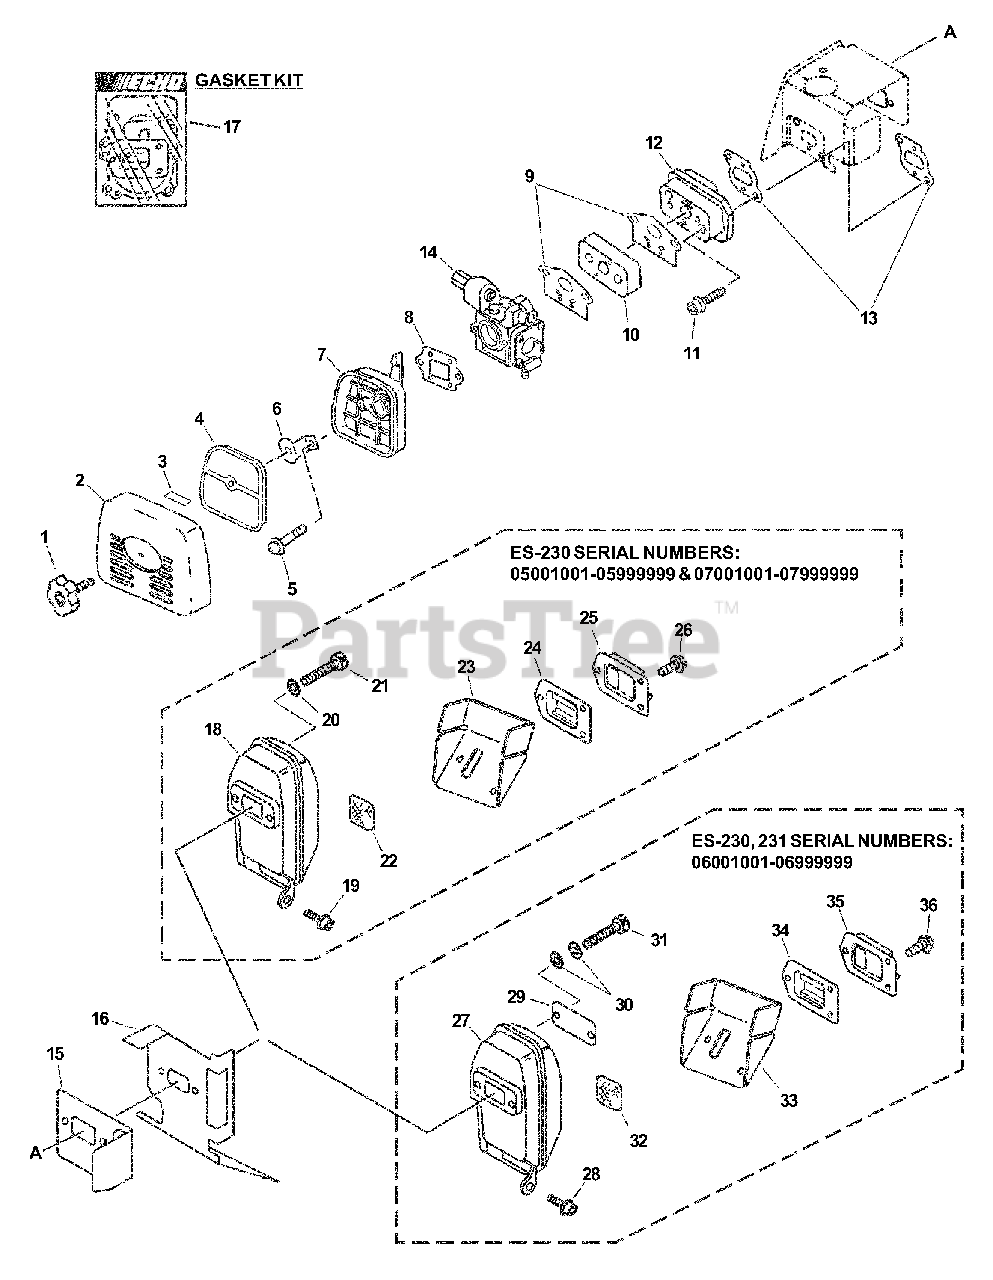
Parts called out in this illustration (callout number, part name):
1	THUMBSCREW
2	COVER, AIR FILTER
3	LABEL - CHOKE
4	FILTER, AIR - HEAVY DUTY
5	SCREW - 5X65
6	PLATE, PREVENT
7	CASE, AIR FILTER
9	GASKET, INTAKE
10	INSULATOR, INTAKE
11	SCREW - 5X25
12	INSULATOR, INTAKE
13	GASKET, INTAKE
14	CARBURETOR
15	GASKET, EXHAUST
16	SHIELD, EXHAUST
17	GASKET KIT
18	MUFFLER
19	SCREW - 5X16
20	WASHER - 5
21	SCREW - 5X60
22	SCREEN, SPARK ARRESTOR
23	GASKET, EXHAUST
24	GUIDE, EXHAUST - INNER
25	GUIDE, EXHAUST
26	SCREW - 4X10
27	MUFFLER
28	SCREW - 5X16
29	PLATE
30	WASHER - CONICAL
31	BOLT - 5X65
32	SCREEN, SPARK ARRESTOR
33	GASKET, EXHAUST
34	GUIDE, EXHAUST - INNER
35	GUIDE, EXHAUST
36	SCREW - 4X12
